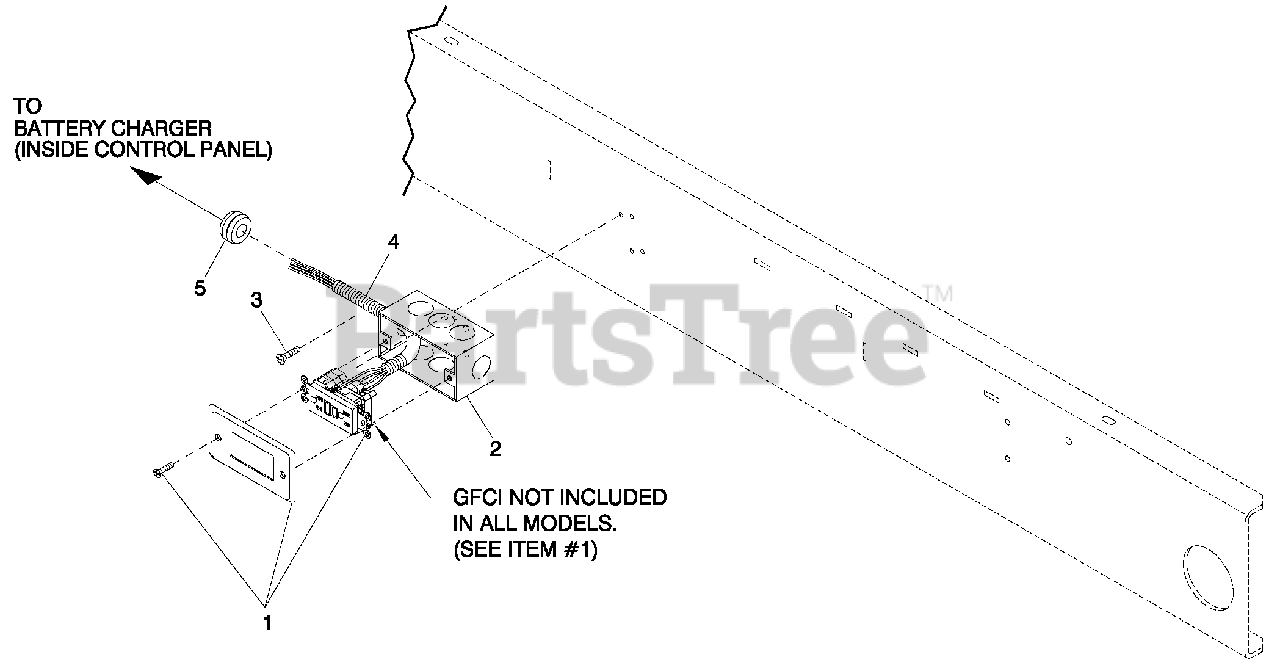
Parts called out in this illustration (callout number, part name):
1	OUTLET 20A GFCI
2	BOX HANDY 2-1/8 X 4
3	SCREW HHTT #10-24 X 3/8 CZ
4	HARN ALT CON BOX 1PH QT
5	GROMMET .87 X .25 X .62
